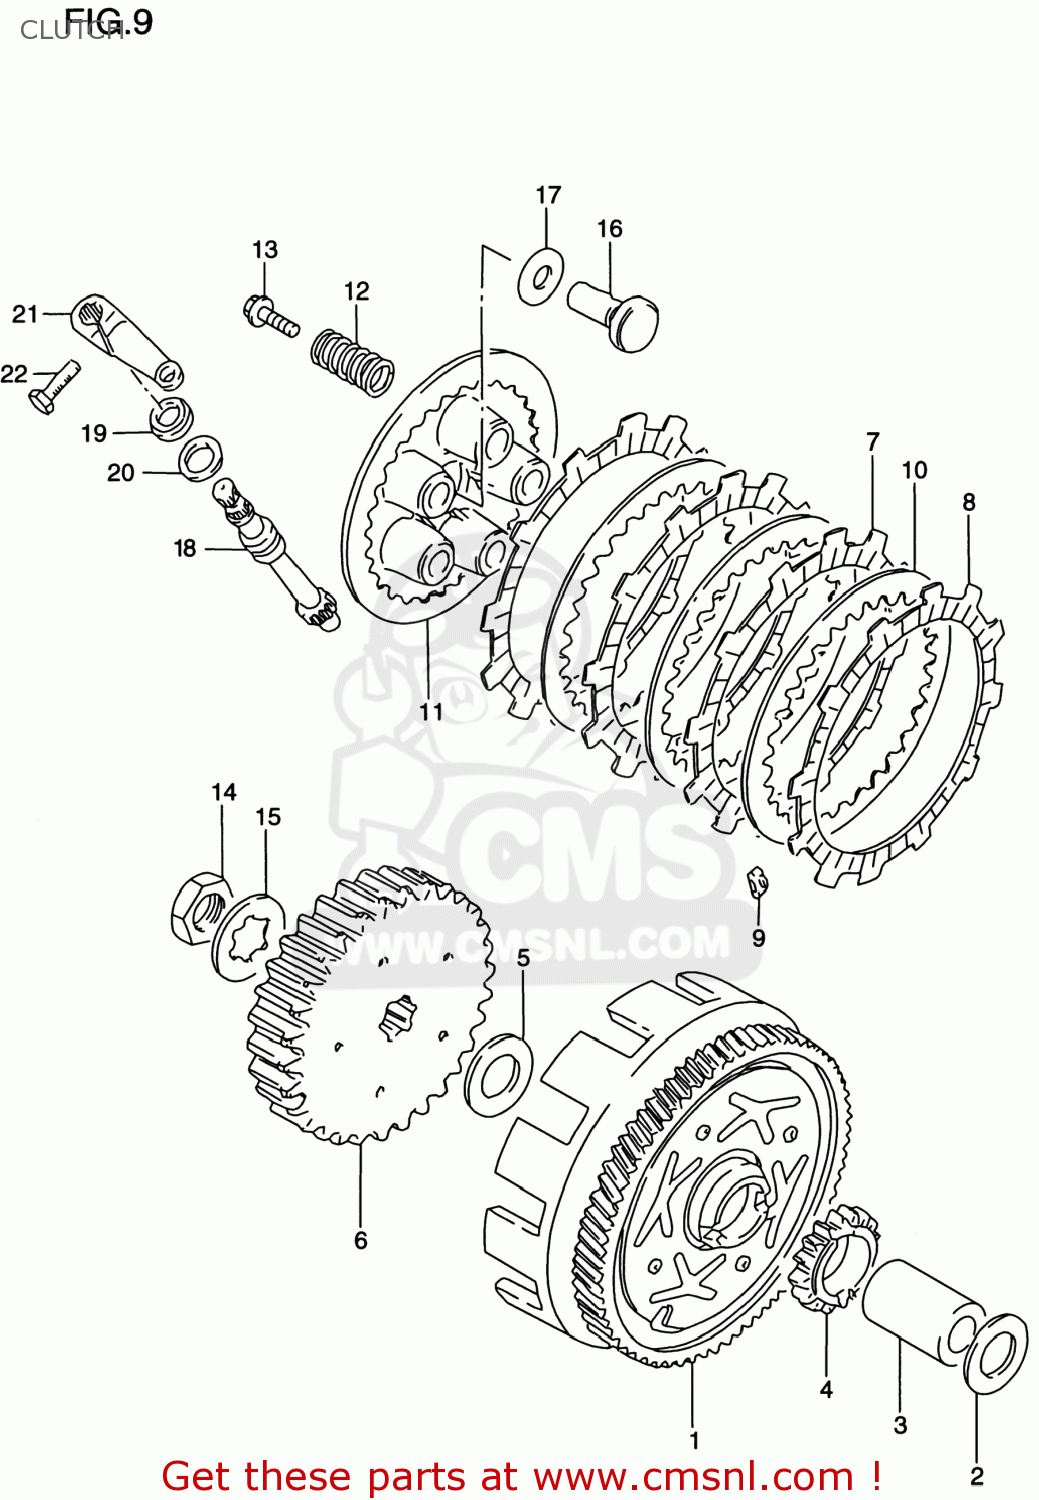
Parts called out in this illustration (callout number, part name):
1	GEAR ASSY,PRI DRIVEN(NT:73)
2	WASHER,THRUST
3	SPACER,PRIMARY DRIVEN GEAR
4	GEAR,KICK STARTER DRIVE
5	WASHER
6	HUB,CLUTCH SLEEVE
7	PLATE,CLUTCH DRIVE(T:3.0) (NAS)
8	PLATE,CLUTCH DRIVE (NAS)
9	DAMPER
10	PLATE,CLUTCH DRIVEN (NAS)
11	DISC,CLUTCH PRESSURE
12	SPRING
13	BOLT 5X16
14	NUT
15	WASHER,LOCK
16	RACK,CLUTCH RELEASE
17	BEARING(10X22X2.8)
18	PINION,CLUTCH RELEASE
19	SEAL,OIL(10X17X5)
20	WASHER
21	ARM,CLUTCH RELEASE
22	BOLT
